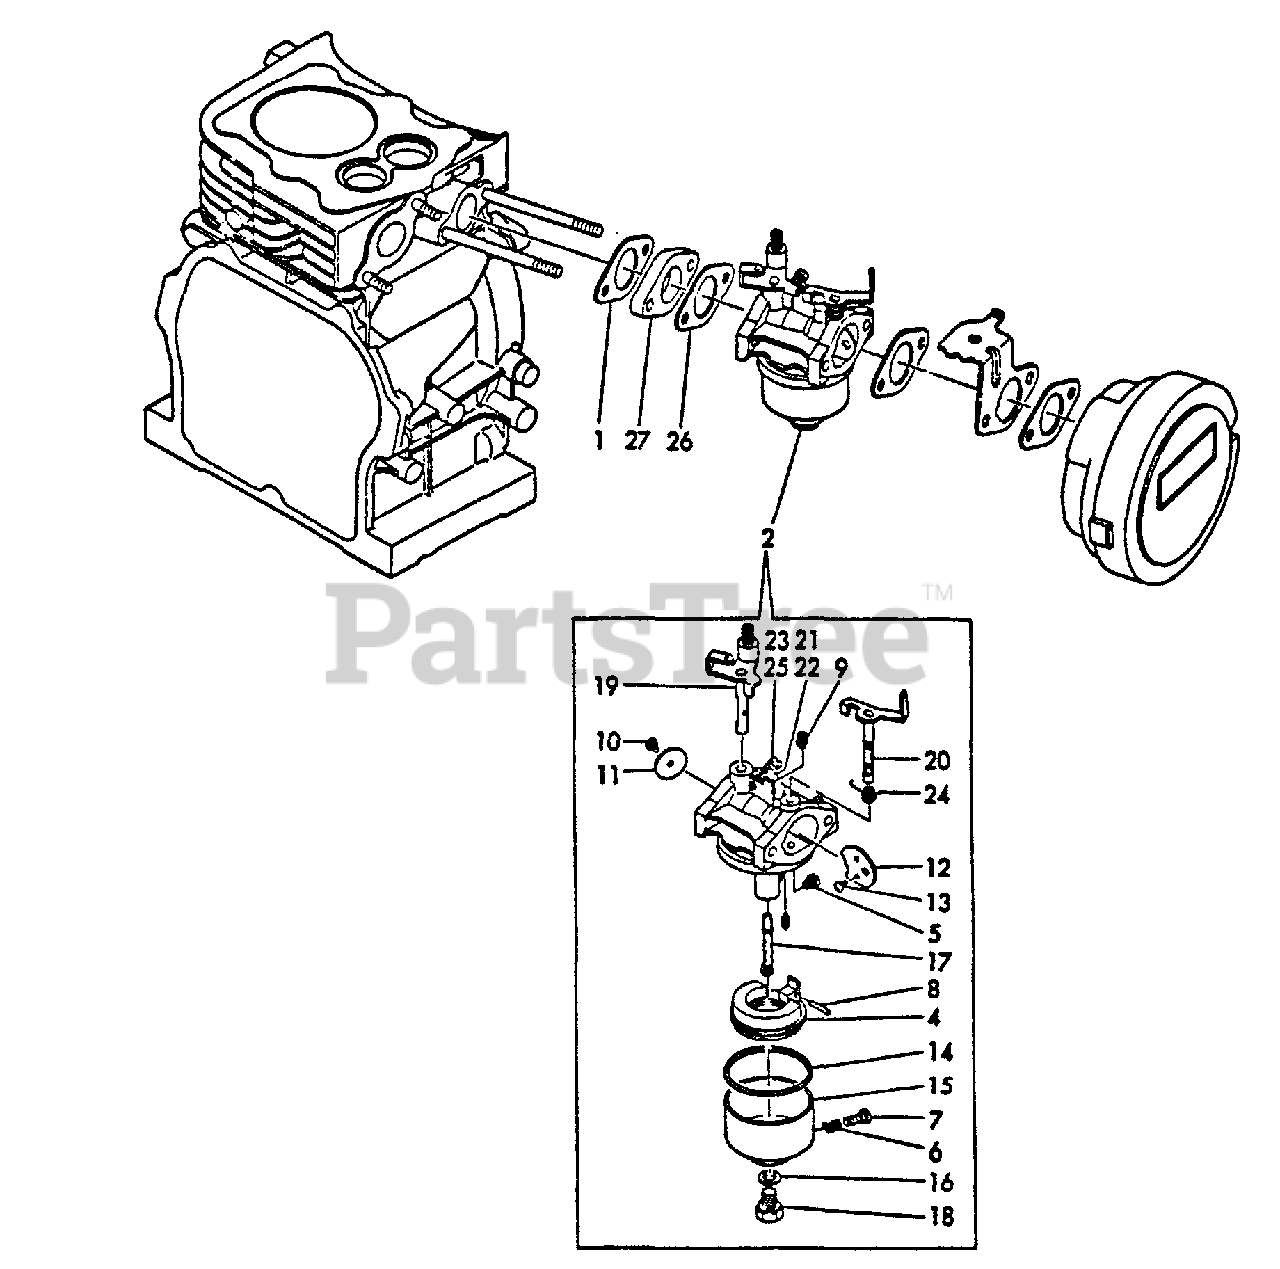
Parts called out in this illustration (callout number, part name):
1	GASKET, EXHAUST
2	CARBURETOR
4	FLOAT
5	JET, MAIN
7	SCREW
8	PIN
9	JET, PILOT
10	SCREW
11	VALVE, THROTTLE
12	VALVE, CHOKE
14	GASKET
15	BODY, FLOAT CHAMBER
16	GASKET
17	NOZZLE
18	BOLT
19	SHAFT ASSY, THROTTLE
20	SHAFT, CHOKE
21	SCREW
22	SPRING
23	SCREW, PILOT
24	SPRING
25	SPRING
26	GASKET, INTAKE
27	SPACER
